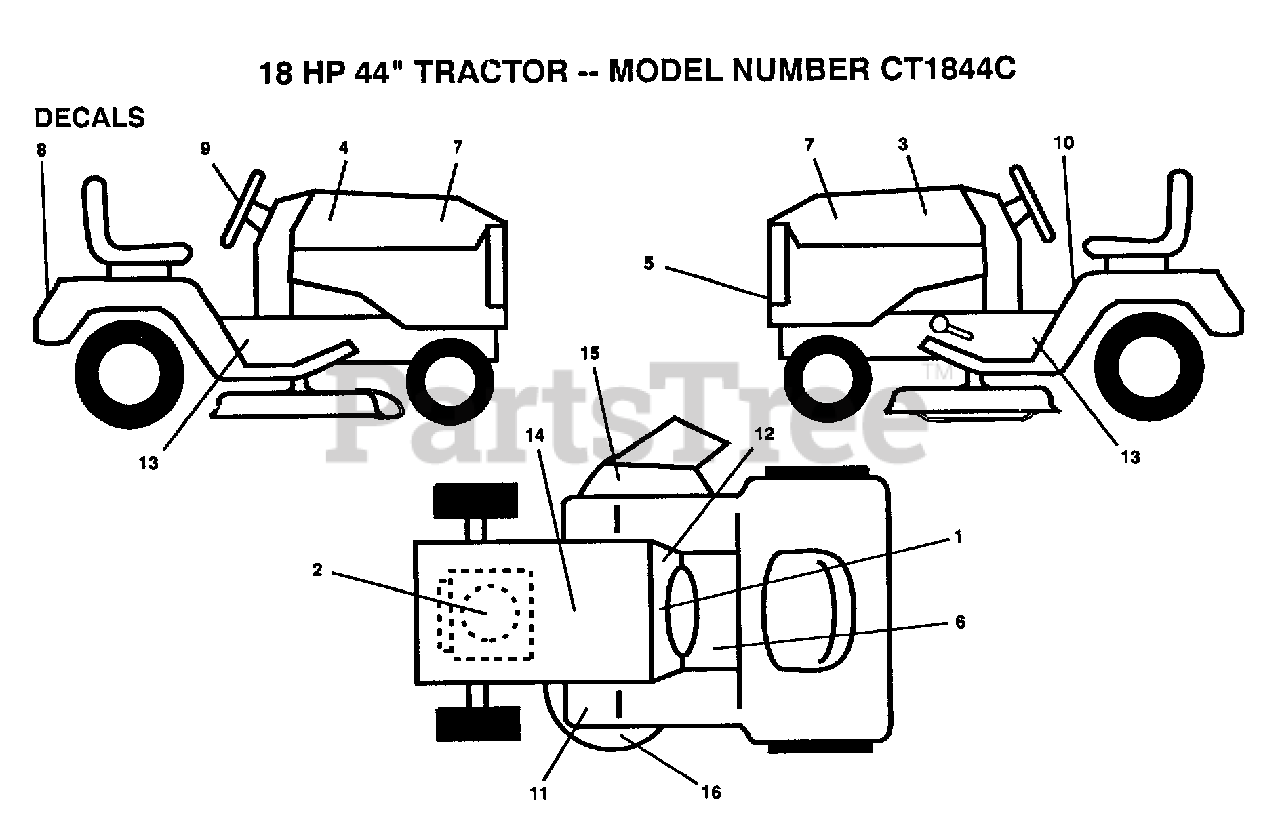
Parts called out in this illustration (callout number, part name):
2	DECAL.ENG.272559
7	DECAL PANEL T
8	"DECAL,FENDER"
10	DECAL CAUTION
11	DECAL T
14	DECAL
15	DECAL WARING
16	DECAL YT
